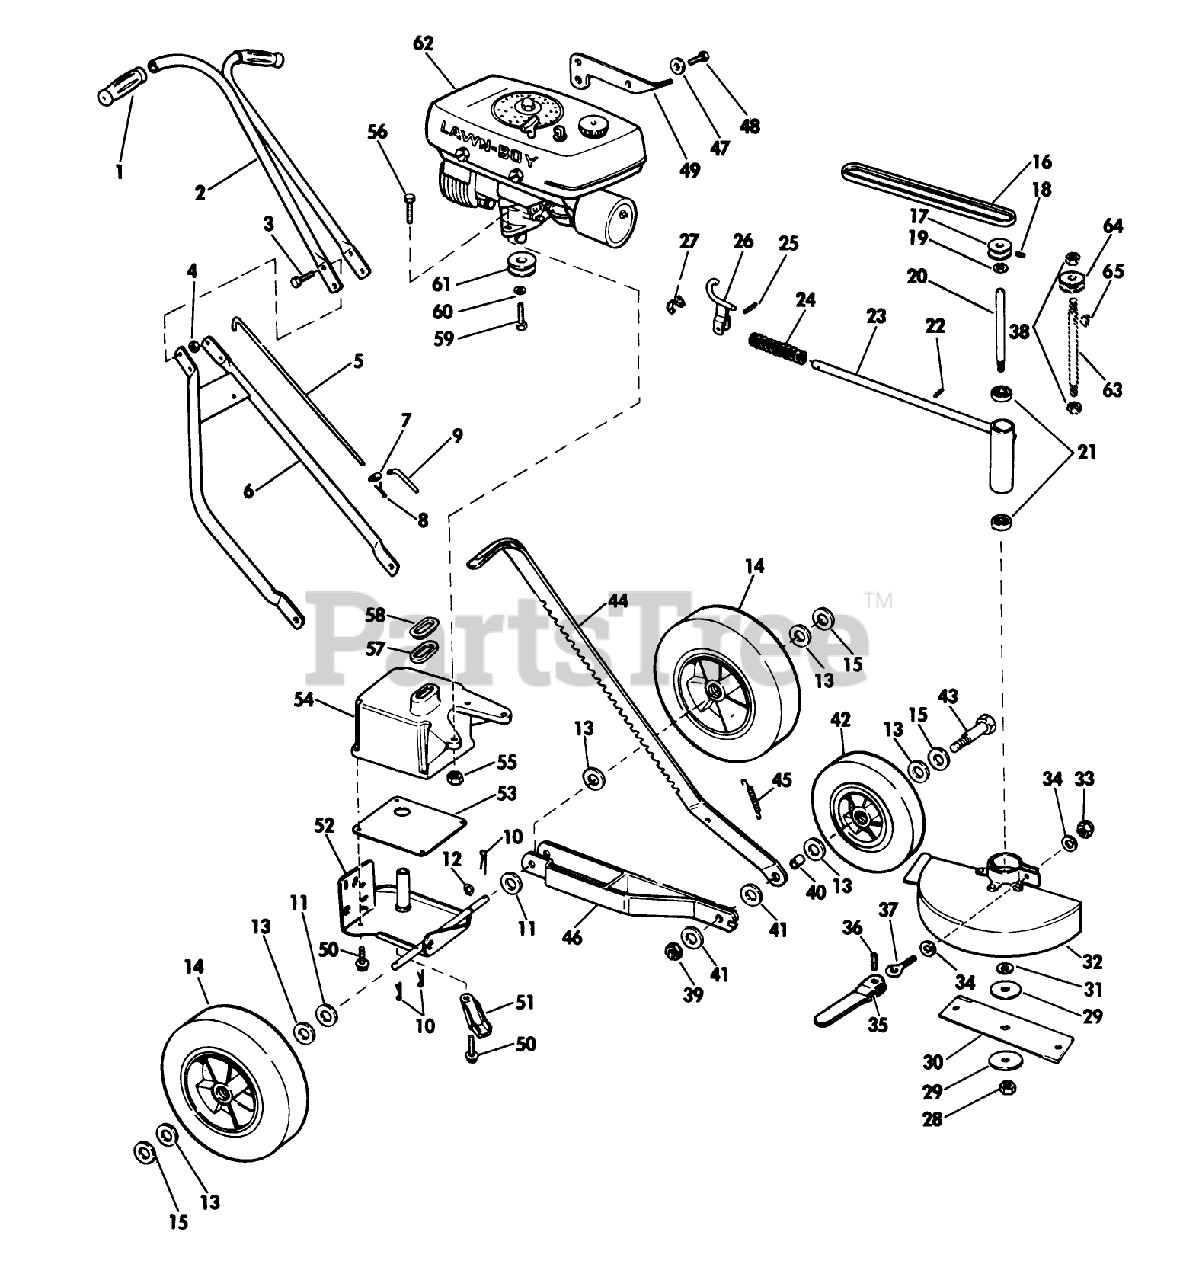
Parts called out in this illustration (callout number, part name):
1	HANDLE GRIP
3	SCREW
13	WASHER
14	Wheel and Tire Assembly 8"
15	SPACER
30	Blade-9"
31	WASHER
36	Roll Pin
39	LOCKNUT
43	BOLT
48	Screw
55	NUT
56	BOLT F
57	GASKET S
58	SLEEVE
60	WASHER, LOCK
